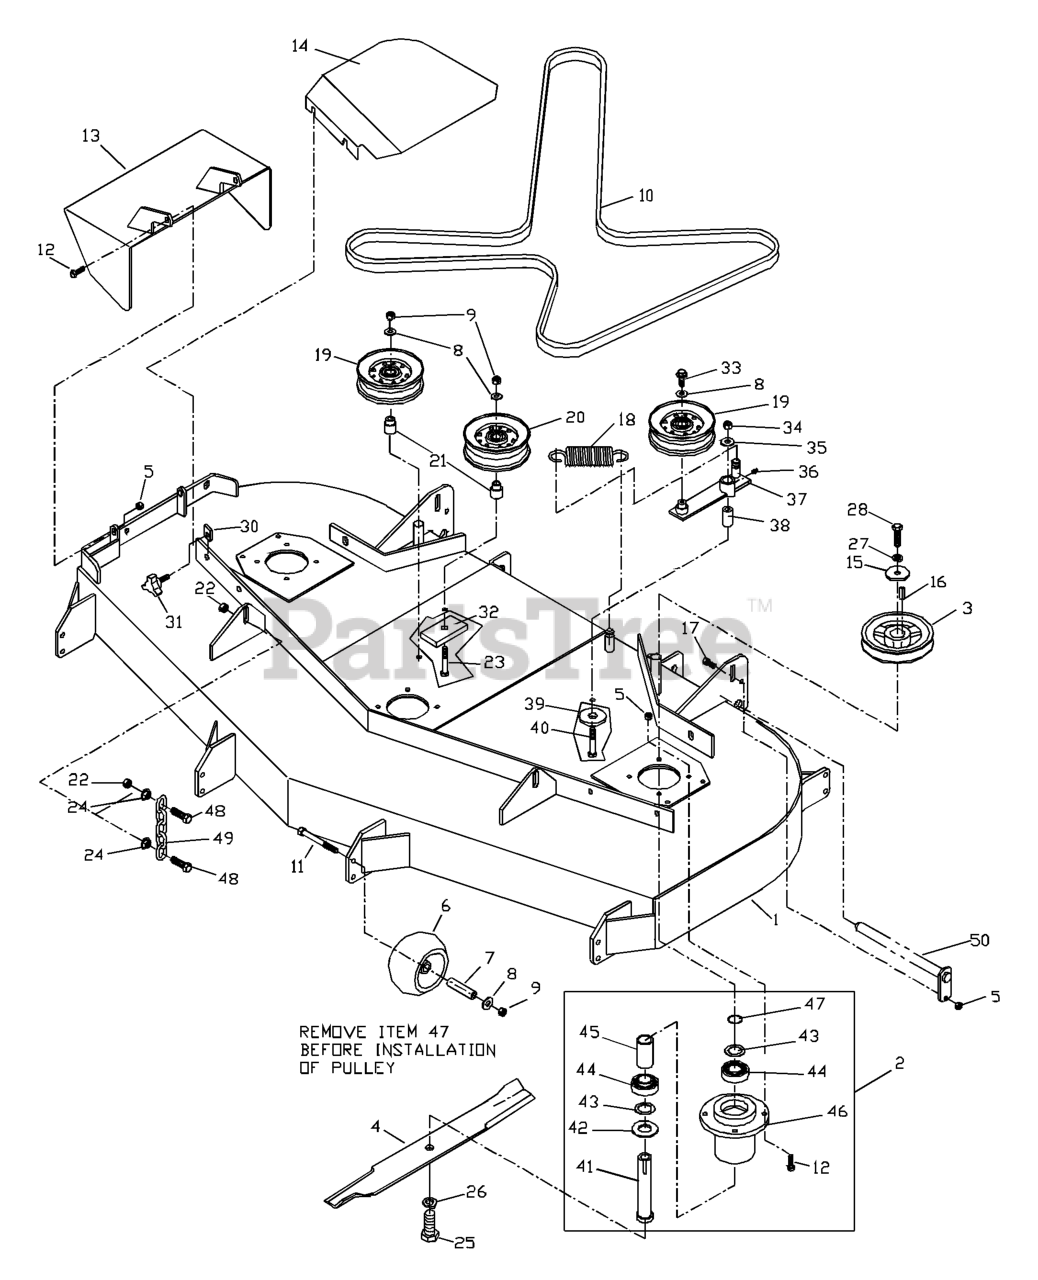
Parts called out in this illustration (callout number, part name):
1	DECK W/DECALS 61" HUS
1	DECK W/DECALS 52" HUS WSL
2	HOUSING ASM.
3	PULLEY 52" DECK
4	BLADE OEM 21" (61" DECK)
4	BLADE OEM 18"
5	NUT 5/16C CENTERLOCK
6	ANTI-SCALP ROLLER
8	WASHER 3/8 FLAT
9	NUT 3/8C CENTERBLOCK
10	DECK BELT 61
10	BELT, DECK
11	HCS 3/8C X 3 1/2
12	HCS 5/16C X 1
13	DISCHARGE CHUTE
14	61 B.S.PAINTED, RT
14	52 B.S.PAINTED,RT
15	WASHER, CRANKSHAFT
16	KEY 1/4 SQ X 1 1/8
17	HCS 5/16C X 3/4
18	DECK SPRING
19	IDLER PULLEY
20	IDLER PULLEY (TALL)
21	IDLER BUSHING
22	NUT 7/16C CENTERLOCK
23	HCS 3/8C X 2 1/2
24	NUT 7/16C WHIZ
25	HCS 5/8F X 1 1/4
26	LOCKWASHER 5/8
27	WASHER 7/16 LOCK
28	HCS 7/16F X 1 1/2
29	61 B.S.PAINTED, LT ORANGE
29	52 B.S.PAINTED, LT
30	U-CLIP 5/16-18 NUT RETAINER
31	KNOB W/STUD
32	SUPPORT PLATE
33	4CS 3/8C X 1 SERRATED HEAD
34	NUT 1/2-13 HEX NYLOC ZD
35	WASHER 1/2 FLAT
36	ZERK
38	PIVOT BUSHING
39	WASHER, SUPPORT
40	HCS 1/2C X 3 1/4
42	MACHINERY BUSHING 10 GA.
43	BUSHING.MACHINE.18.GAUGE
44	BEARING
46	HOUSING, DIE CAST
48	HCS 7/16C X 1 1/2
49	LIFT CHAIN
